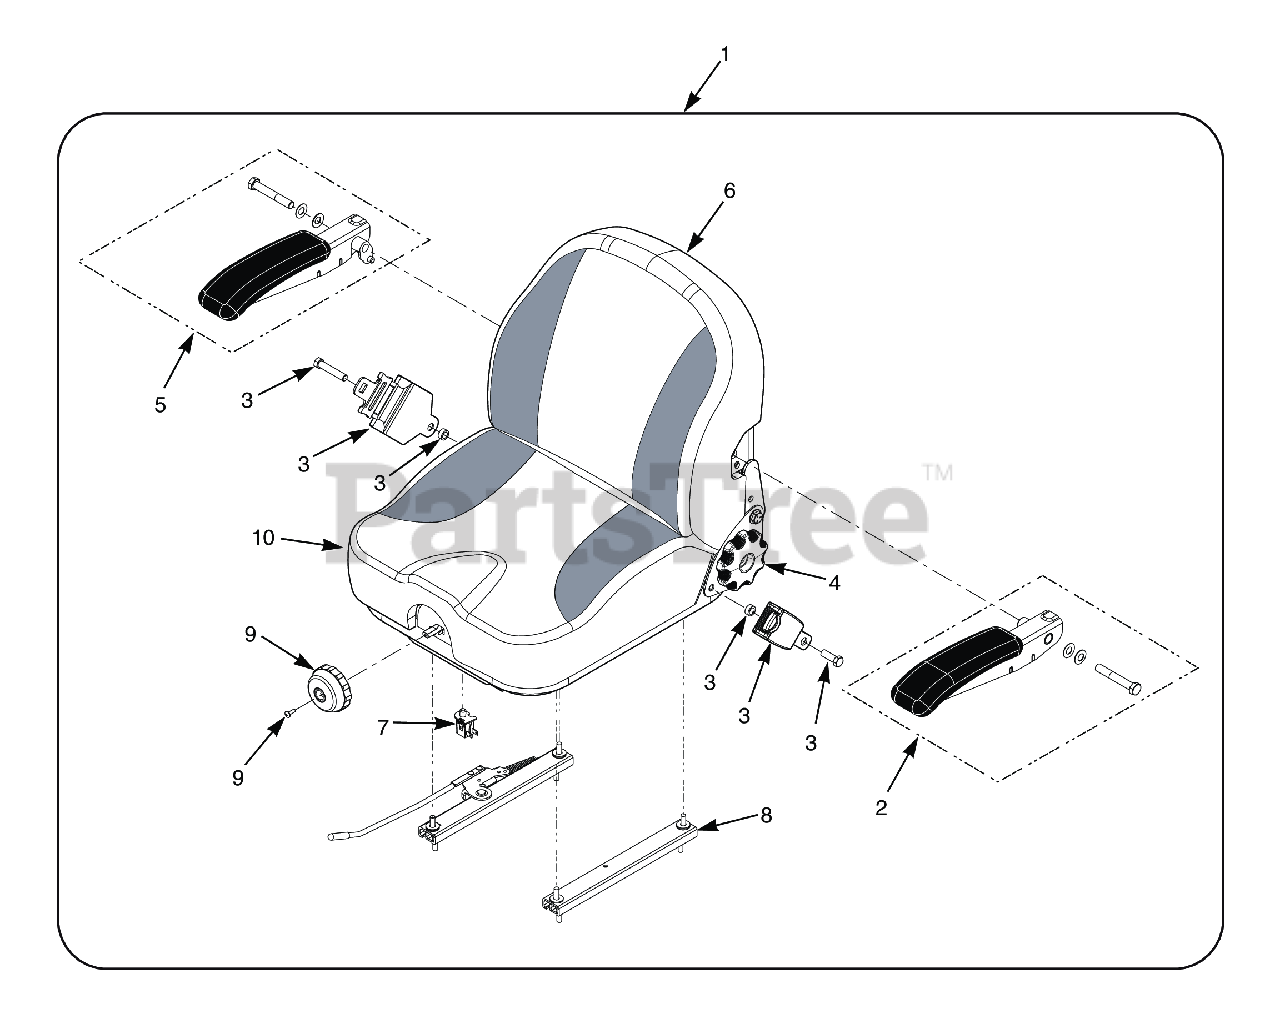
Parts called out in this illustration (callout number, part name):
1	Suspension Seat Assembly w/seat belt
2	Armrest Kit, LH
3	Seat Belt Kit (Suspension Seat)
4	Knob Kit, Recliner
5	Armrest Kit, RH
6	Cover, Back Cushion
7	Switch, Interlock, Normally Open
8	Track Kit
9	Knob Kit, Weight Adjust
10	Cover, Seat Cushion
